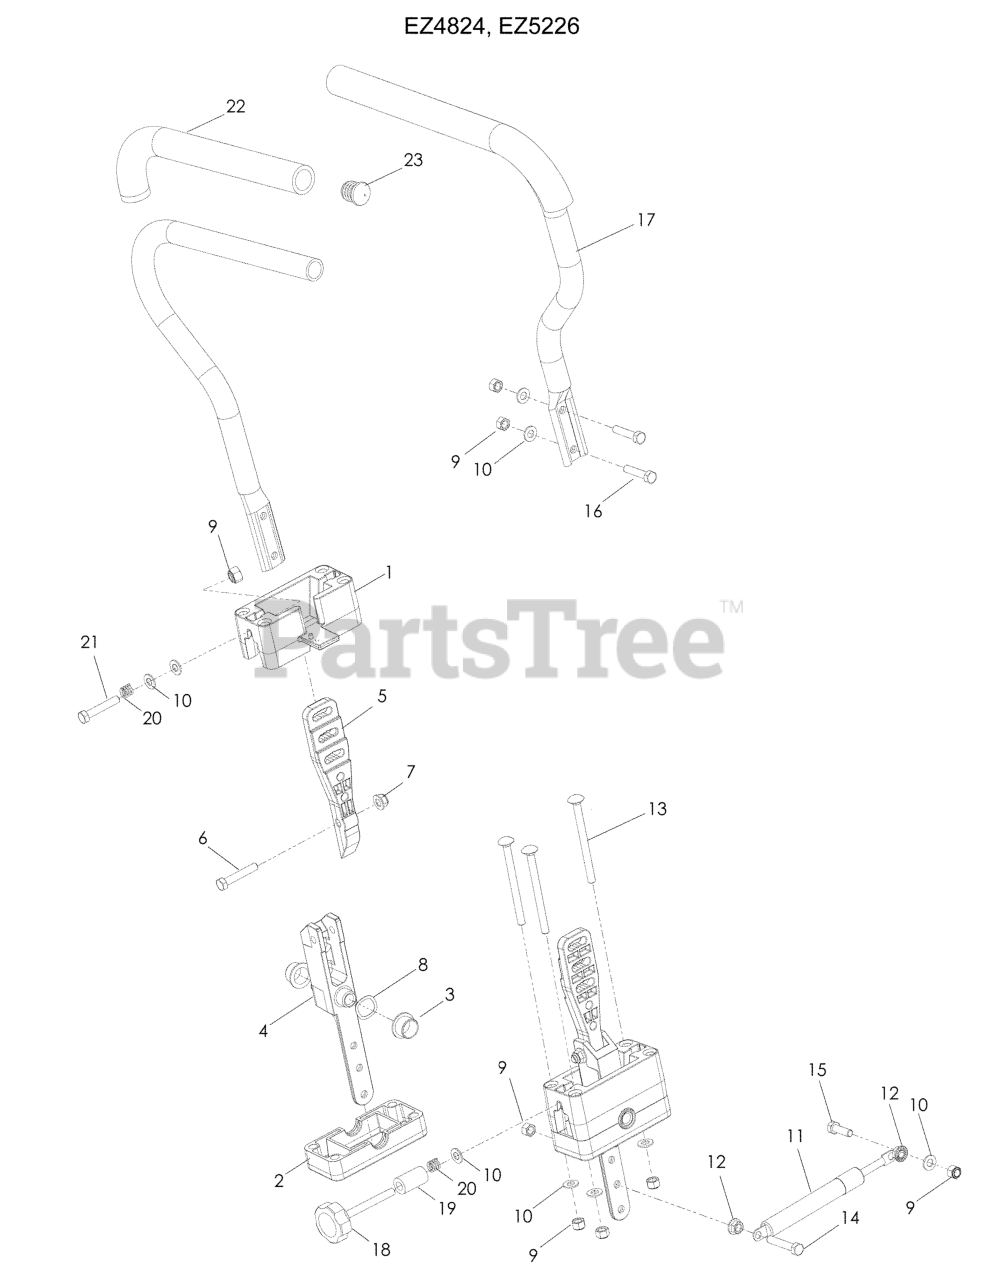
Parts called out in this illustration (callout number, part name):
1	BLOCK, UPPER
2	BLOCK, LOWER
3	BEARING, FLANGE
4	PIVOT.SECTION.DRIVE.CONTROL
5	MOUNT, DR CNTRL HANDLE
6	HCS 5/16C X 1 3/4
7	5/16-18 NYLOC FLANGE NUT
8	WASHER, .825 X 1.087, WAVE
9	NUT 5/16 NYLOC
10	FLAT WASHER 5/16 SAE
12	NUT 5/16C WHIZ
13	RHSNB 5/16-18 X 4 GR 5 ZD
14	HCS 5/16-18X1-3/4 TPBLT
15	HCS 5/16C X 1
16	CAPSCREW 5/16 X 1/1/2 HEX HEAD
17	LEVER.DRIVE.W/GRIP
19	DECK LIFT SPACER
21	HCS 5/16-18 X 2 TPBLT GR 5 ZD
22	GRIP, FOAM (GROUND) 15
23	END PLUG 15/16 (BLACK)
